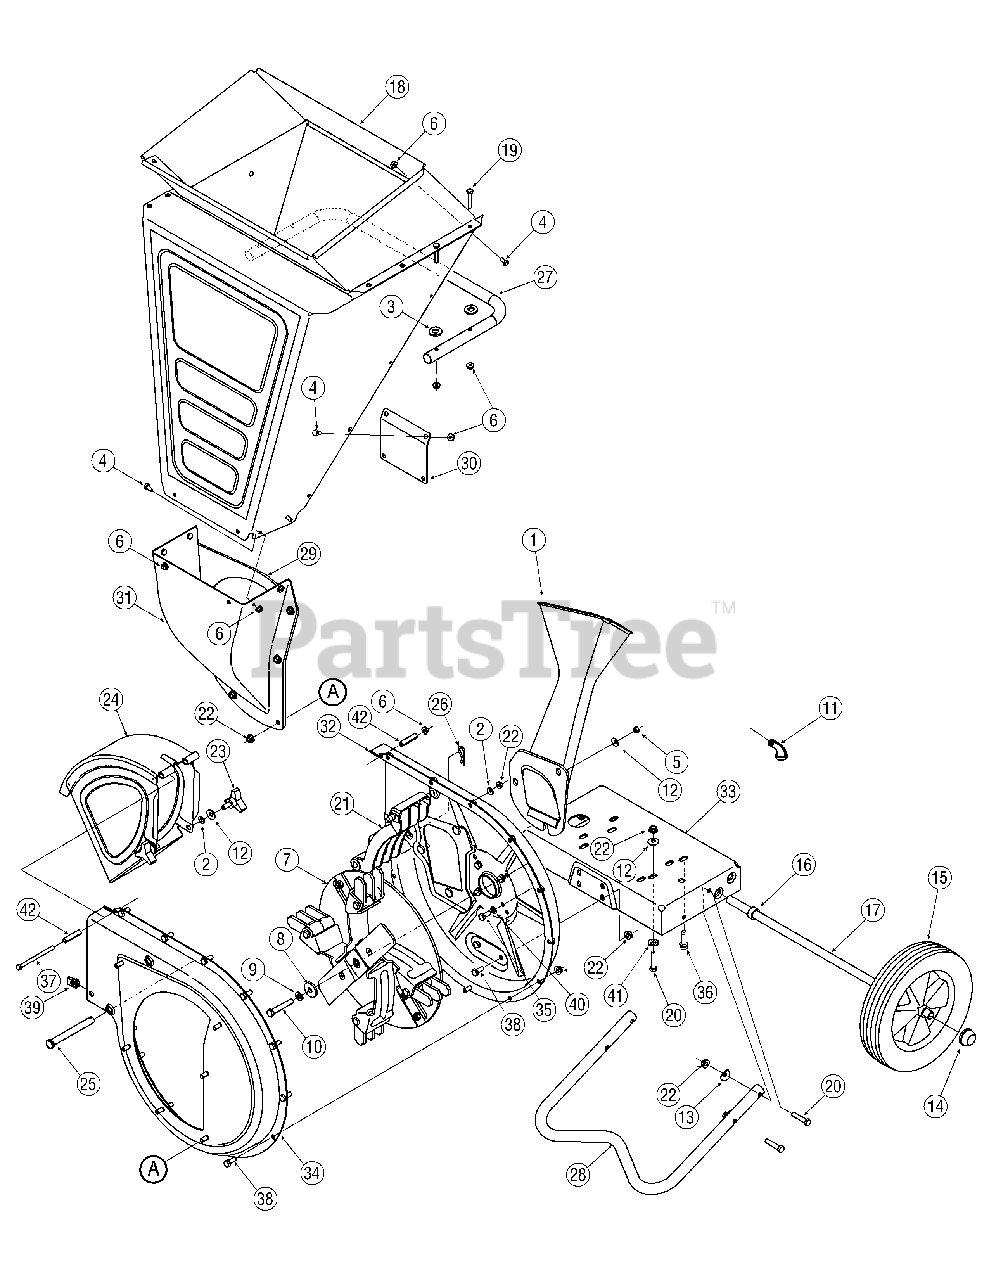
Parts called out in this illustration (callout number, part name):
2	Speed Nut, .3125ID
3	Flat Washer, .28 x.74 x.063
4	Hex Cap Screw, 1/4-20 x.5
5	Hex Nut, 5/16-18
6	Hex Lock Nut 1/4-20
7	Impeller Assembly
8	Flat Washer,.406 x 1.25
9	Lock Washer, 3/8
10	Hex Cap Screw, 3/8-24 x 2.2
11	Elbow Fitting
12	Bell Washer.340 ID x.872 OD
13	Washer,.320 ID x.93 OD
14	Push Cap, 5/8
15	Wheel, 10 x 2.5
16	Spacer, .64 x .88 x .38
17	Axle, 22.47"
19	Hex Cap Screw, 1/4-20 x 1.25
20	Hex Cap Screw, 5/16-18 x 1.50
21	Shredder Screen
22	Flange Lock Nut, 5/16-18
23	Knob Assembly (Incl. ref.# 12 & 61)
25	Clevis Pin, .50 x 4.62
26	Internal Cotter Pin
35	Hex Cap Screw, 5/16-24 x.75
36	Hex Sems Screw, 3/8-16 x 1.25
37	Hex Cap Screw, 1/4-20 x 3.75
38	Hex Cap Screw, 5/16-18 x.625
39	U-Nut, 5/16-18
40	Lock Washer, 5/16
41	Special Lock Washer, 5/16
42	Hinge Spacer,.265 x.380 x 1.66
